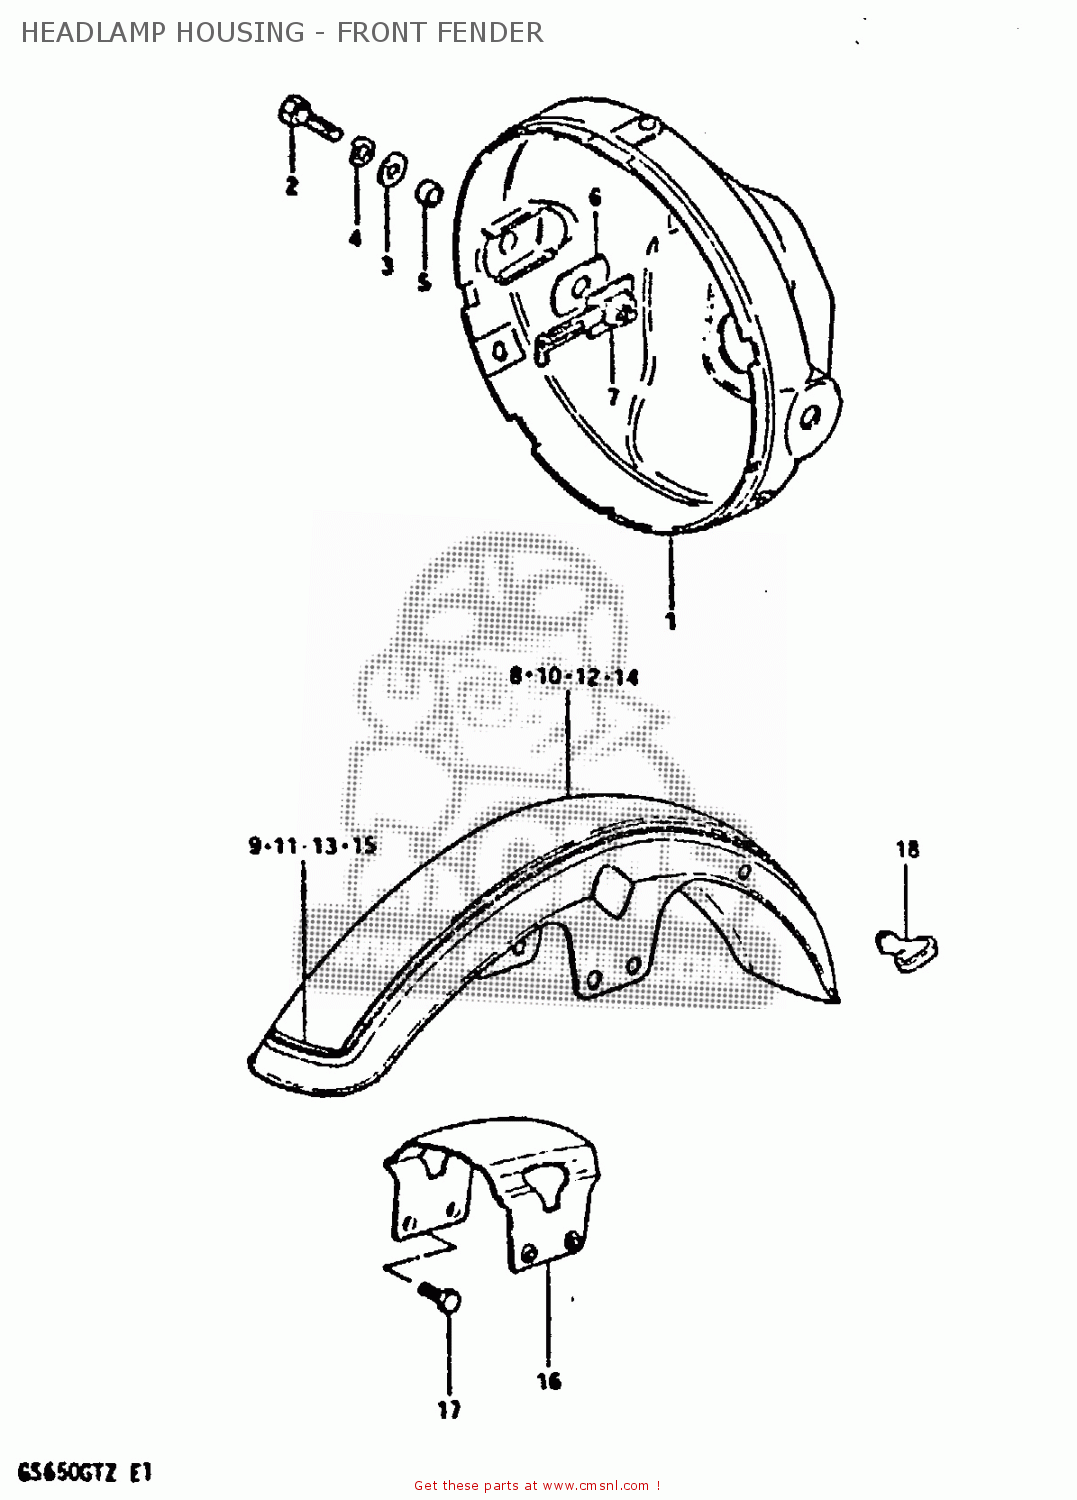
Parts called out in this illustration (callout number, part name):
1	HOUSING,HEADLAMP
2	BOLT
3	WASHER
4	LOCK WASHER
5	SPACER (8.8X12X7)
6	CUSHION
7	PLATE,HEADLAMP HOUSING
8	FENDER,FRONT
9	TAPE,FRONT FENDER
10	FENDER,FRONT
11	TAPE,FRONT FENDER
12	FENDER,FRONT
13	TAPE,FRONT FENDER
14	FENDER, FRONT (BLACK, CANDY IMPERIAL MA
15	TAPE SET,FRONT FENDER
16	BRACE,FRONT FENDER
17	BOLT 8X16
18	GUIDE,CABLE
